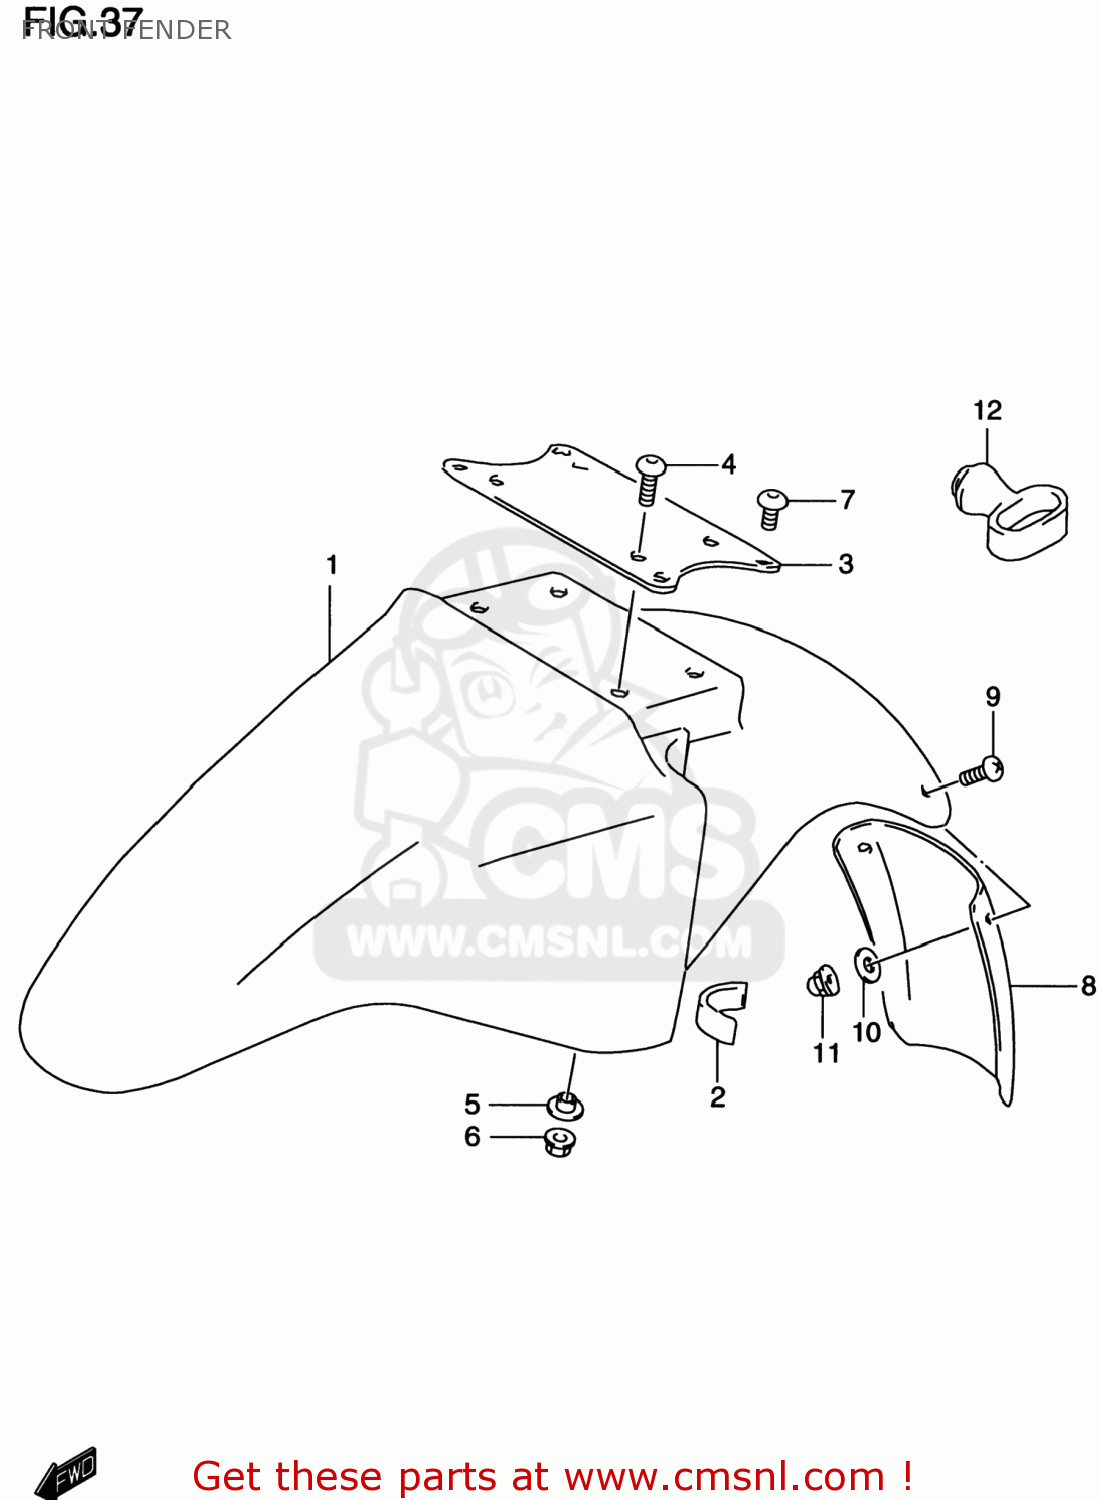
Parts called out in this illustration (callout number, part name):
1	FENDER,FRONT
2	CUSHION,FR FENDER
3	BRACE,FR FENDER
4	SCREW(5X16)
5	WASHER
6	NUT
7	SCREW(6X12)
8	MUDGUARD,FR FENDER
9	SCREW
10	WASHER(5.5X20X1.2)
11	NUT
12	GUIDE,CABLE
